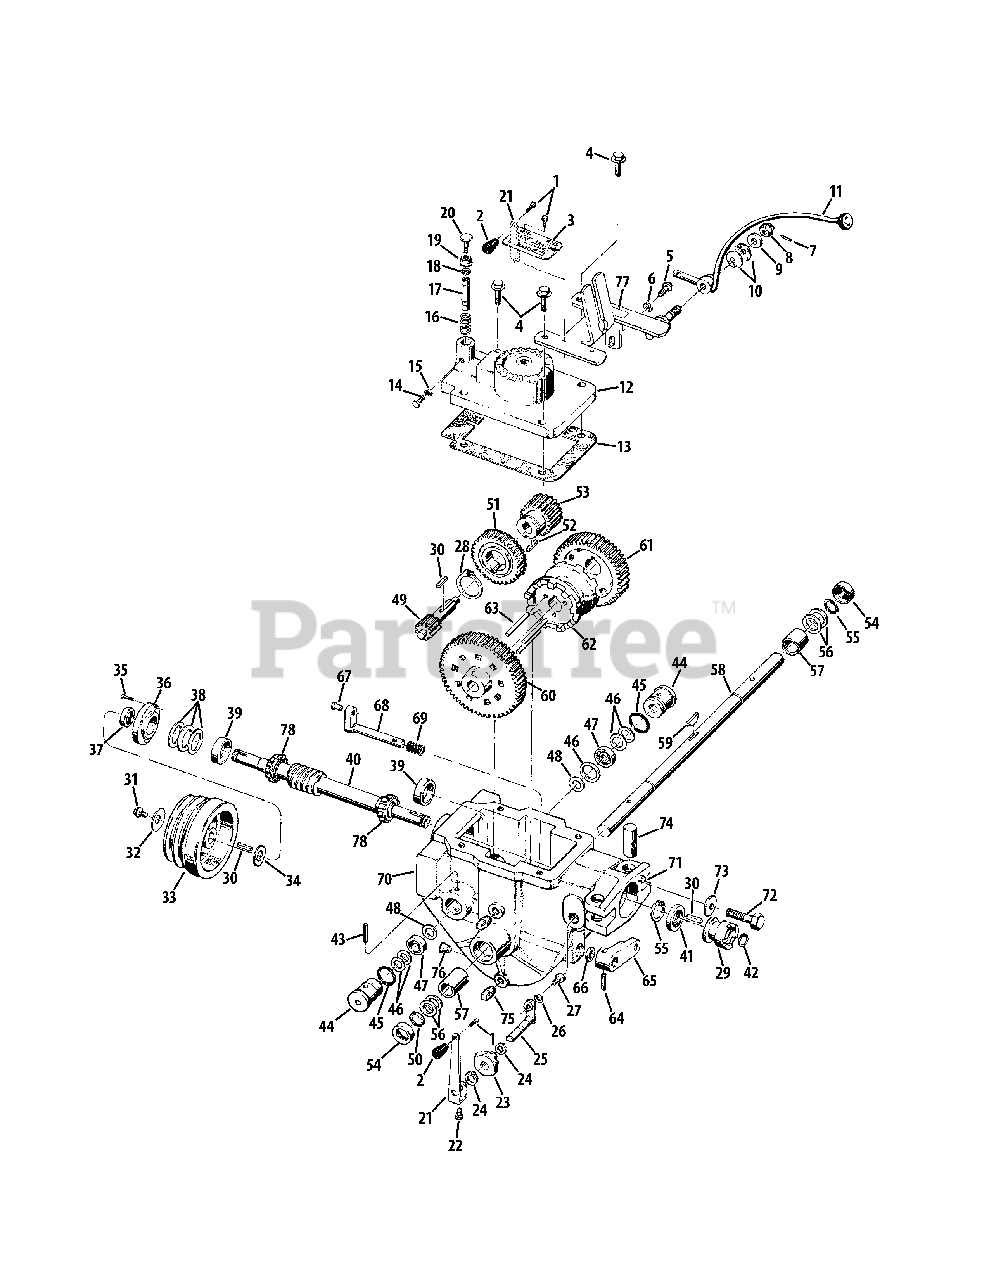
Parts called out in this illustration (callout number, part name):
1	Hex Head Screw, #10-32 x 3/8"
4	Hex Flange Bolt, 3/8"-16 x 1-1/2"
5	Hex Flange Bolt, 5/16"-18 x 3/4"
6	Flat Washer, 5/16"
7	Spring Pin, 1/8"
8	Hex Nut, 1/2"-20
8	Flat Washer, .510 x 1.0 x .125
9	Shoulder Washer, 1.25 x .50 x .25
10	Disc Spring Washer, 1.97 x 1.0 x .118
11	Wheel Speed Shift Lever
12	Power Unit Transmission Cover
13	Transmission Cover Gasket
14	Hex Head Screw, 5/16"-18 x 1"
15	Hex Nut, 5/16"-18
16	Plunger Spring
18	Clip Ring
19	Flange Lock Nut, 3/8"-16
20	Screw, 3/8"-16 x 1-1/2"
21	Tines/PTO Clutch Lever
22	Hex Head Screw, 1/4"-20 x 1/2"
23	Tines/PTO Clutch Bushing
24	External Retaining Ring
25	Tines/PTO Clutch Shaft
26	Hi-Collar Lockwasher, 1/4"
27	Socket Head Screw, 1/4"-20 x 3/8"
28	External Retaining Ring
29	Dog Clutch
30	Key, 3/16" x 1"
31	Hex Head Screw, 5/16"-24 x 3/4"
32	Spring Washer, .827 x .331 x .098
33	Transmission Drive Pulley
34	Flat Washer, 1.25 x .687 x .075
35	Flange Nut, 1/4"-20 x .75
36	Front Bearing Cap
38	Flat Washer, 1.175 x 1.5 x .062
38	Flat Washer, 1.175 x 1.5 x .005
38	Flat Washer, 1.175 x 1.5 x .03
38	Flat Washer, 1.175 x 1.5 x .01
39	Cup Bearing
40	Main Drive Shaft
42	Retaining Ring
43	Roll Pin (Spirol), 1/4" x 2
44	Pinion Bearing
46	Flat Washer, 1.234 x 1.015 x .062
46	Flat Washer, 1.234 x 1.015 x .033
46	Flat Washer, 1.234 x 1.015 x .01
47	Ball Bearing
48	Washer
49	Pinion Stem
50	External Retaining Ring, 1.387 ID
51	Worm Gear
52	Key, 3/16" x 5/8"
53	Fast Speed Pinion Gear
55	External Retaining Ring
56	Flat Washer, 1.375 x 1.015 x .005
56	Flat Washer, 1.375 x 1.015 x .01
56	Flat Washer, 1.375 x 1.015 x .015
56	Flat Washer, 1.375 x 1.015 x .03
56	Flat Washer, 1.375 x 1.015 x .062
57	Bushing, 1.25 x 1.005 x 1.5
58	Wheel Shaft
59	Hi-Pro Key, .250 x 1.8125
60	Slow Speed Gear
61	Faste Gear Speed
62	Dog Clutch
63	Clutch Guide Pin, 1/4"
64	Spring Pin, 3/16" x 1-1/4"
65	Wheel Speed Shifting Lever
67	Wheel Speed Shifting Pin
68	Wheel Speed Shifting Shaft
70	Transmission Housing
71	Alignment Pin
72	Hex Screw, 1/2"-13 x 2"
73	Disc Spring Washer
75	Pipe Plug, 1/4"
76	Plug-Red Plastic
77	Clutch Bracket
78	Cone Bearing
